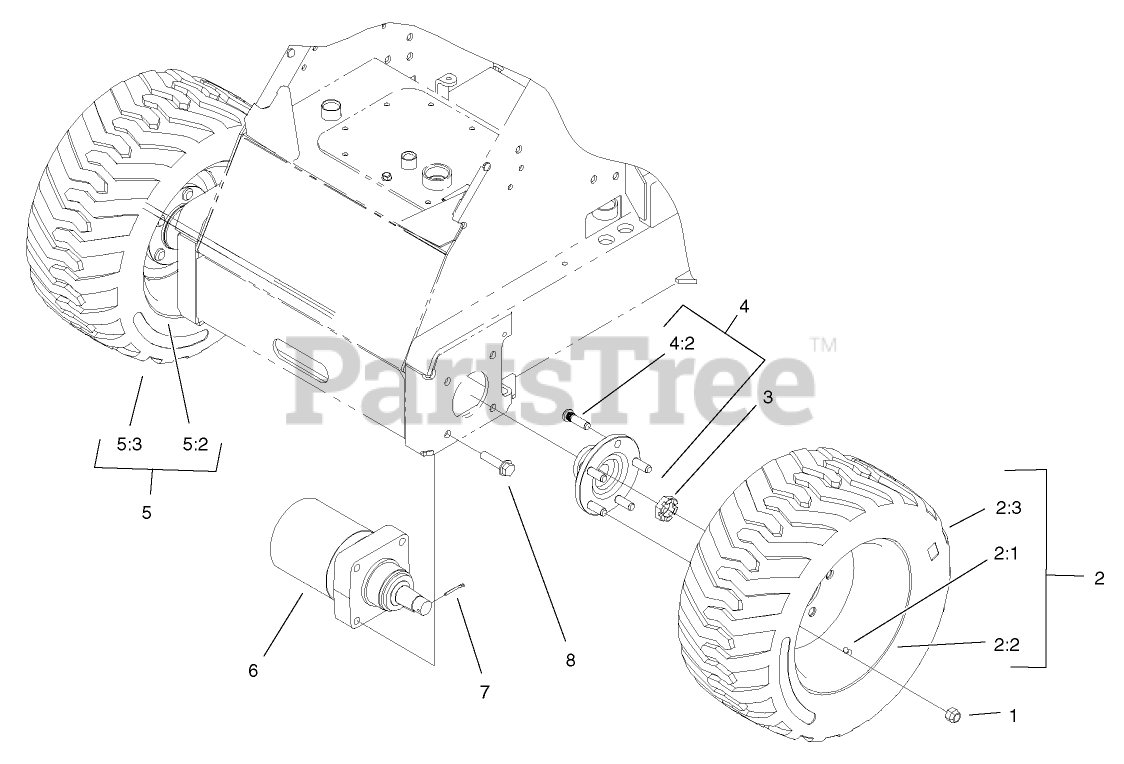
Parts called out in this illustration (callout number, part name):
1	NUT-LUG
2	LH WHEEL AND TIRE ASM
2:1	STEM-VALVE
2:2	WHEEL
4	HUB ASM
4:2	STUD-TYPE, DRIVE
5	RH WHEEL AND TIRE ASM
5:1	STEM-VALVE
5:2	WHEEL
6	HYD MOTOR ASM
7	PIN-COTTER
8	SCREW-HHF
